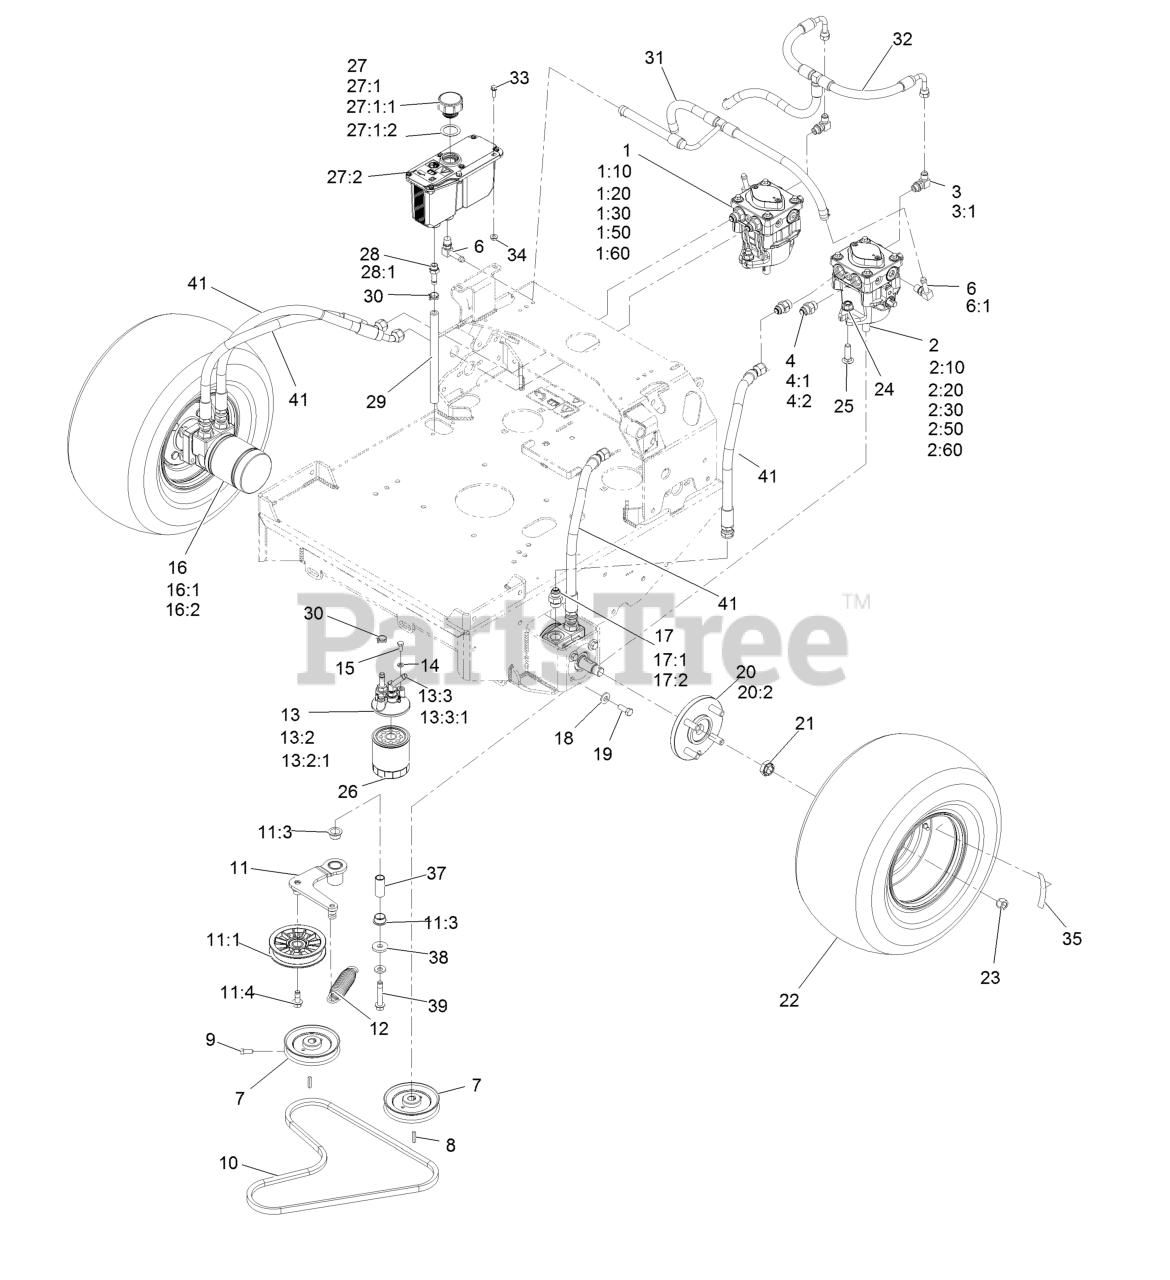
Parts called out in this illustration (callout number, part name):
1	Pump-HYD Pe RH TTH
1:10	Input Shaft Kit
1:20	Bearing-Thrust
1:30	Cylinder Block Kit
1:50	Seal Overhaul Kit
1:60	Kit, 10Cc Pump Kit
2	Pump-HYD Pe LH TTH
2:10	Input Shaft Kit
2:20	Bearing-Thrust
2:30	Cylinder Block Kit
2:50	Seal Overhaul Kit
2:60	Kit, 10Cc Pump Kit
3	Fitting-Elbow, 90 DEG
3:1	O-Ring
4	Adapter-Straight
4:1	O-Ring-SAE #8
4:2	O-Ring-37 Flare #8
6	Fitting-Elbow, 90
6:1	O-Ring
7	Sheave ASM
8	Key-5Mm X 5Mm X 25Mm
9	Screw-Set, SQH 5/16-18 X 3/4
10	Belt
11	ASM, Pump Idler
11:1	Pulley-Idler, Flat
11:3	Bushing-Flanged
11:4	Screw-Hfh
12	Spring-Extension
13	ASM, Filter Head
13:2	Adapter-Straight
13:2:1	O-Ring
13:3	Fitting-Barbed, 45 DEG
13:3:1	O-Ring
14	Washer-Lock 1/4 Heavy
15	Screw-HH 1/4-20 X 5/8
16	HYD Motor ASM
16:1	Seal Kit
16:2	Bearing And Seal Kit
17	Adapter-Straight
17:1	O-Ring
17:2	O-Ring-37 Flare #8
18	Washer-Spring Disc 3/8
19	Screw-HH 3/8-16 X 1
20	Wheel Hub ASM
20:2	Stud-Wheel
21	Nut-Lock
22	Tire And Wheel Assy
23	Nut-Lug 1/2-20
24	Nut-HF, NI
25	Bolt-Carriage 7/16-14 X 1 1/2
26	Element, Oil Filter
27	ASM, HYD Reservoir
27:1	Reservoir-HYD
27:1:1	Cap-Reservoir, HYD
27:1:2	Gasket-Cap
27:2	Decal-Warning
28	Adapter-Straight
28:1	O-Ring
29	Hose-Charge
30	Clamp-Hose 11/16
31	Hose, Case
32	Hose, Charge
33	Screw-Machine 1/4-20 X 3/4
34	Nut-Whizlock 1/4-20
35	Decal-Torque Wheel Lug-Hub
37	Pivot, Idler
39	Screw-HHF W/ Patch
41	Hose,Hydraulic W/Cover
